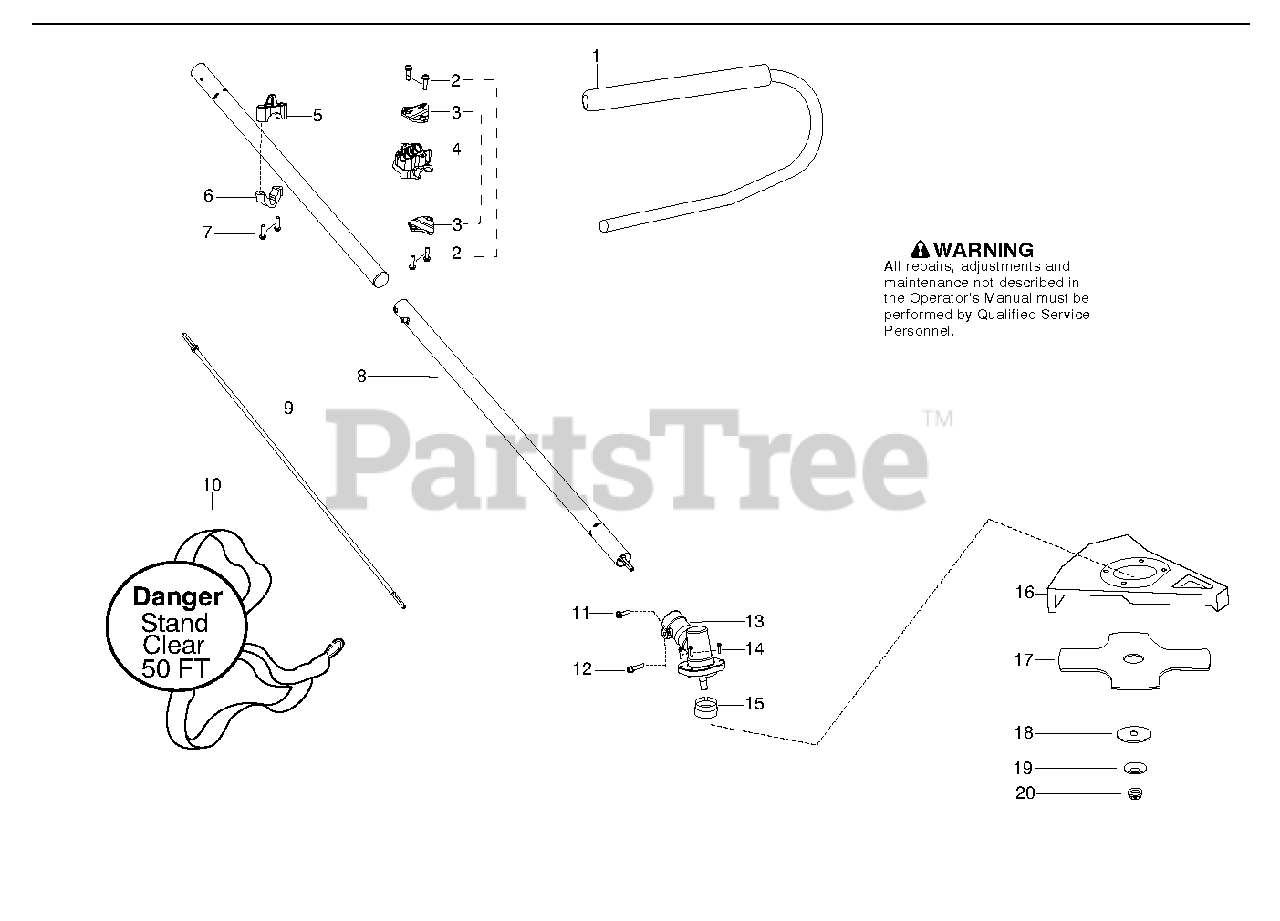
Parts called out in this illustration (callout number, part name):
1	KIT,HANDLEBAR (IN.GRIP,CAP,DCA
2	SCREW-10-14 X 13/16 (PL
3	CLAMP BRACKET
5	CLAMP HARNESS - UPPER
6	CLAMP HARNESS - LOWER
7	SCREW #10 PLASTITE 1.362
9	FLEXSHAFT
10	ASSY,SHOULDER STRAP
11	SCREW - CARB. ADAPTOR
12	SCREW 8-16 X 9/16 (PLAS
13	KIT GEARBOX BLADE
14	SCR 10-24 MS LDK PAN PH
15	DUST CUP , BLADE
16	KIT,BLADE SHIELD
17	UNI BRUSHCUTTER BLADE
18	WASHER,BLADE RETAINING
19	WASHER BELLVILLE
20	NUT-FLANGE (LH)
